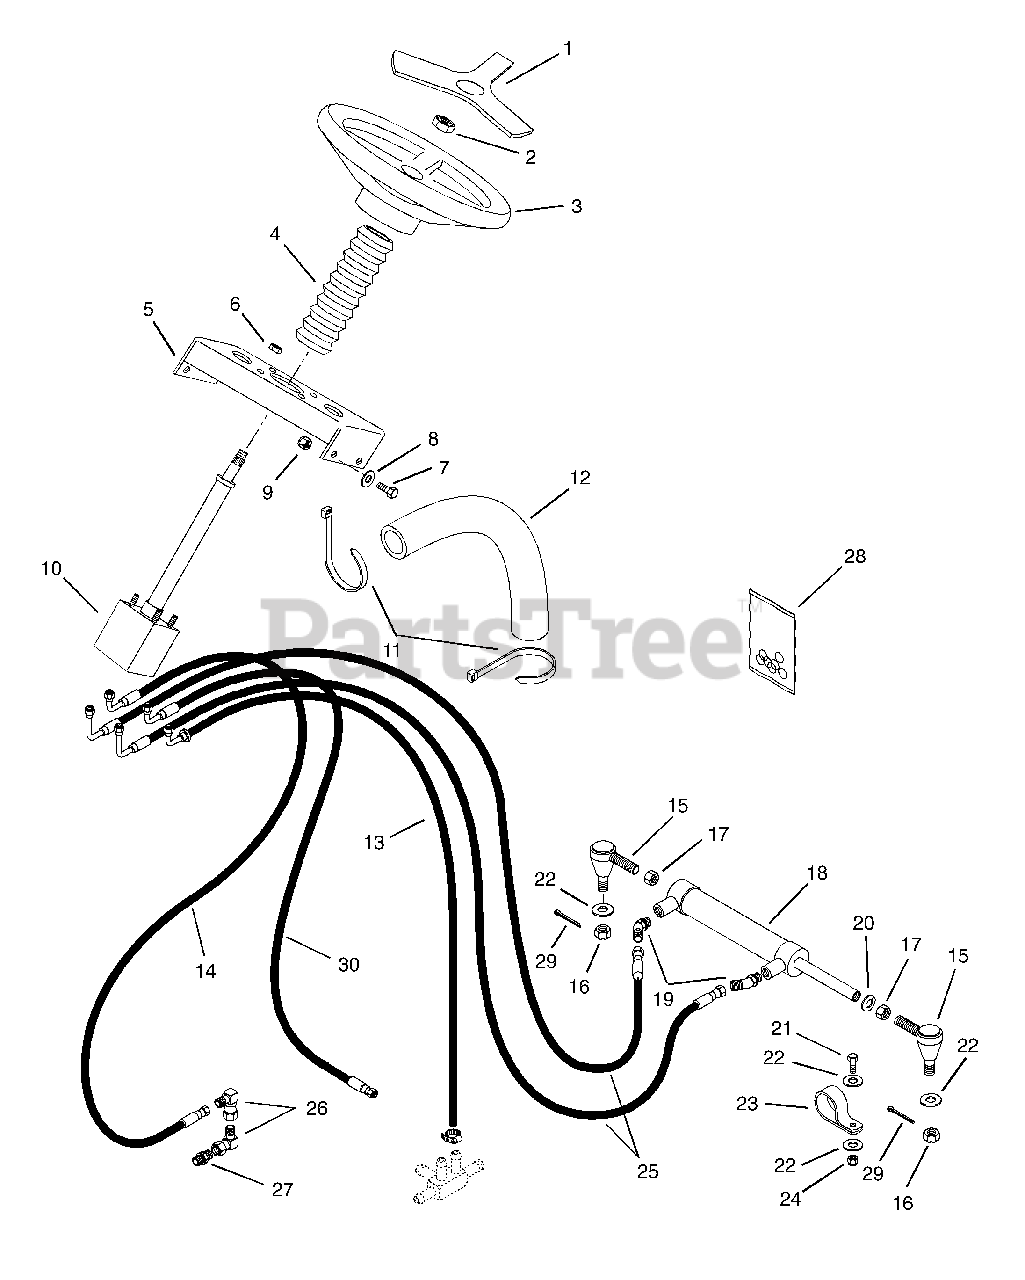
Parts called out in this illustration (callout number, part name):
1	Cap, Steering Wheel
2	Nut-Hex .62-11
3	Steering Wheel
4	Steering Column Boot
5	Bracket, Steering Pump
6	Nut-Locking-Center .31-24
7	Bolt-Hex .31-18 x .75 Grade 5
8	Washer-Flat-Steel .344 x .688 x .065
9	Nut-Locking-Center .31-18
10	Power Steering Unit
11	Tie Wrap, Black
12	Sleeve 12"
13	Assembly, Hydraulic Hose
14	Assembly, Hydraulic Hose
15	Ball Socket-Right Hand
16	Nut-Castle .38-24
17	Nut-Jam .50-20
18	Cylinder, Steering
19	Adapter
20	Washer-Locking .50 X .125
21	Bolt-Hex .38-16 x 1.00 Grade 5
22	Washer-Flat-Steel .406 x .812 x .065
23	Clamp, Nylon
24	Nut-Locking-Nylon .38-16
25	Hydraulic Hose Assembly
26	Adapter
27	Adapter-Pipe .56-18 "O" Ring To .56-18
28	Repair Kit, Power Steering
29	Pin-Cotter .09 x .75
30	Assembly, Hydraulic Hose (Steering to Valve)
